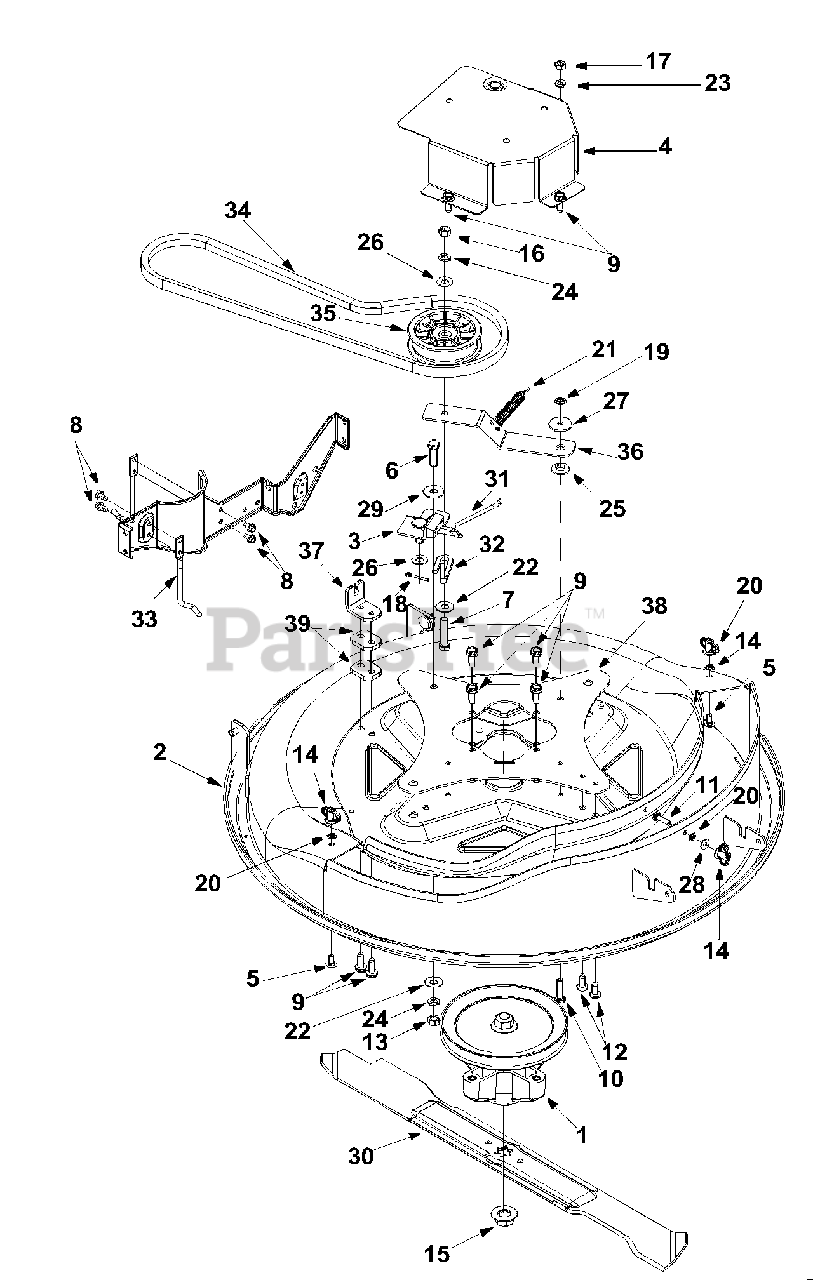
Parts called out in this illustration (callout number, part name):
1	Spindle Assembly
2	Deck Assembly: Red metallic
3	Brake Bracket Assembly
5	Carriage Screw 1/4-20 x .62
6	Hex Bolt 3/8-24 x 1.25 Grade 8
7	Hex Screw 3/8-16 x 1.75 Gr. 5
8	Self-Tapp. Screw 1/4-20 x .5
9	Self-Tapp. Screw 5/16-18 x .75
10	Hex Cap Scr. 5/16-24 x 1.25
11	Carriage Screw
12	Torx Screw 5/16-18 x .75
13	Hex Nut 3/8-24
14	Wing Nut With Bell Washer
15	Flange Nut 5/8-18
16	Hex Nut 3/8-16
17	Hex Nut 5/16-24
21	Extension Spring
22	Flat Washer 3/8 x 1.00 x .030
23	Lock Washer 5/16
24	Lock Washer 3/8
25	Bushing
26	Flat Washer .406 x .875 x .059
27	Flat Washer .330 x 1.25 x .120
29	Spacer
35	Flat Idler Pulley
